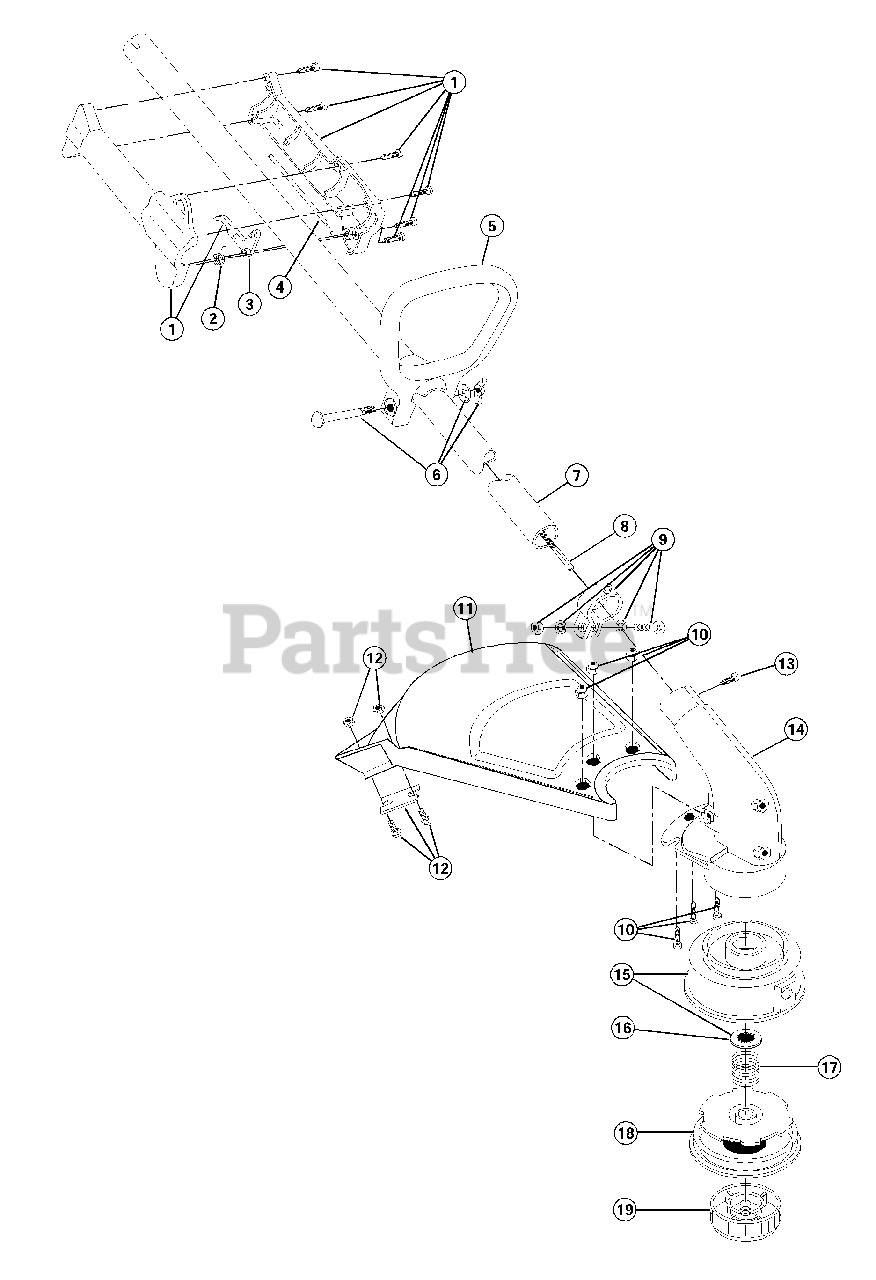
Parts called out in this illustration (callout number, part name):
1	Throttle Housing and Trigger Assembly
2	Throttle Trigger Spring
3	Throttle Trigger
4	Throttle Cable Housing Assembly
5	D-Handle
6	D-Handle Hardware Assembly
7	Drive Shaft Housing Assembly
8	Flexible Drive Shaft
9	Lower Clamp Assembly
10	Guard Mounting Screw Assembly
11	Guard and Blade Assembly
12	Blade Assembly
13	Anti-Rotation Screw
14	Gearbox Assembly
15	Outer Spool and Eyelet Assembly
16	Retainer
17	Spring
18	Inner Reel
19	Bump Head Knob Assembly
